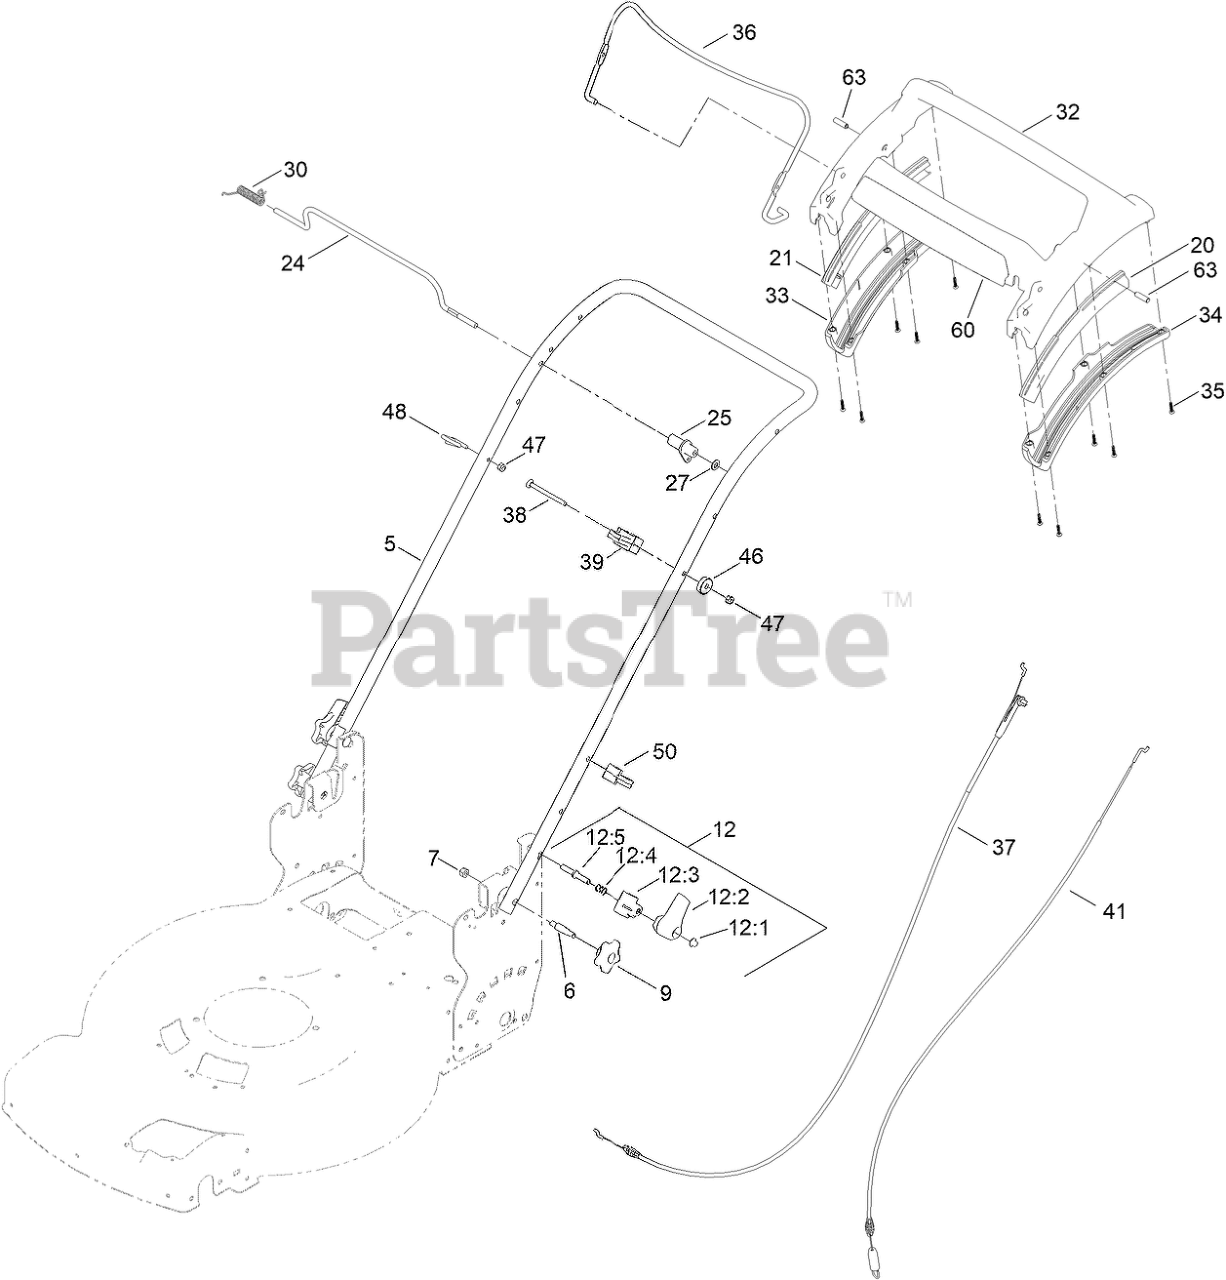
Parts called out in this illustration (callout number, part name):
5	HANDLE-CURVED
6	BOLT-SHOULDER, HANDLE
7	NUT-HEX
9	KNOB-HANDLE
12	QUICK RELEASE ASM
12:1	NUT-PUSH
12:2	LEVER-RELEASE
12:3	ANCHOR-SPRING
12:4	SPRING-COMPRESSION
12:5	ROD-RELEASE
20	GUIDE-CURVED, LH (RWD)
21	GUIDE-CURVED, RH (RWD)
24	ROD-CONTROL, TRACTION
25	LEVER-TRACTION, RWD
27	WASHER-PLAIN
30	SPRING-TORSION
32	HANDLE-PERSONAL PACE, CURVED
33	BOTTOM-HANDLE, RH
34	BOTTOM-HANDLE, LH
35	SCREW-PPH
36	BAIL-BRAKE
37	CABLE-BRAKE, PP BS
38	SCREW-CARR
39	ANCHOR-CABLE, RWD
41	CABLE-TRACTION, RWD (PP)
46	WASHER-CURVED
47	NUT-HEX
48	GUIDE-ROPE
50	GUIDE-CABLE
60	DECAL - ADS, HANDLE
63	PIN-HANDLE, PP
